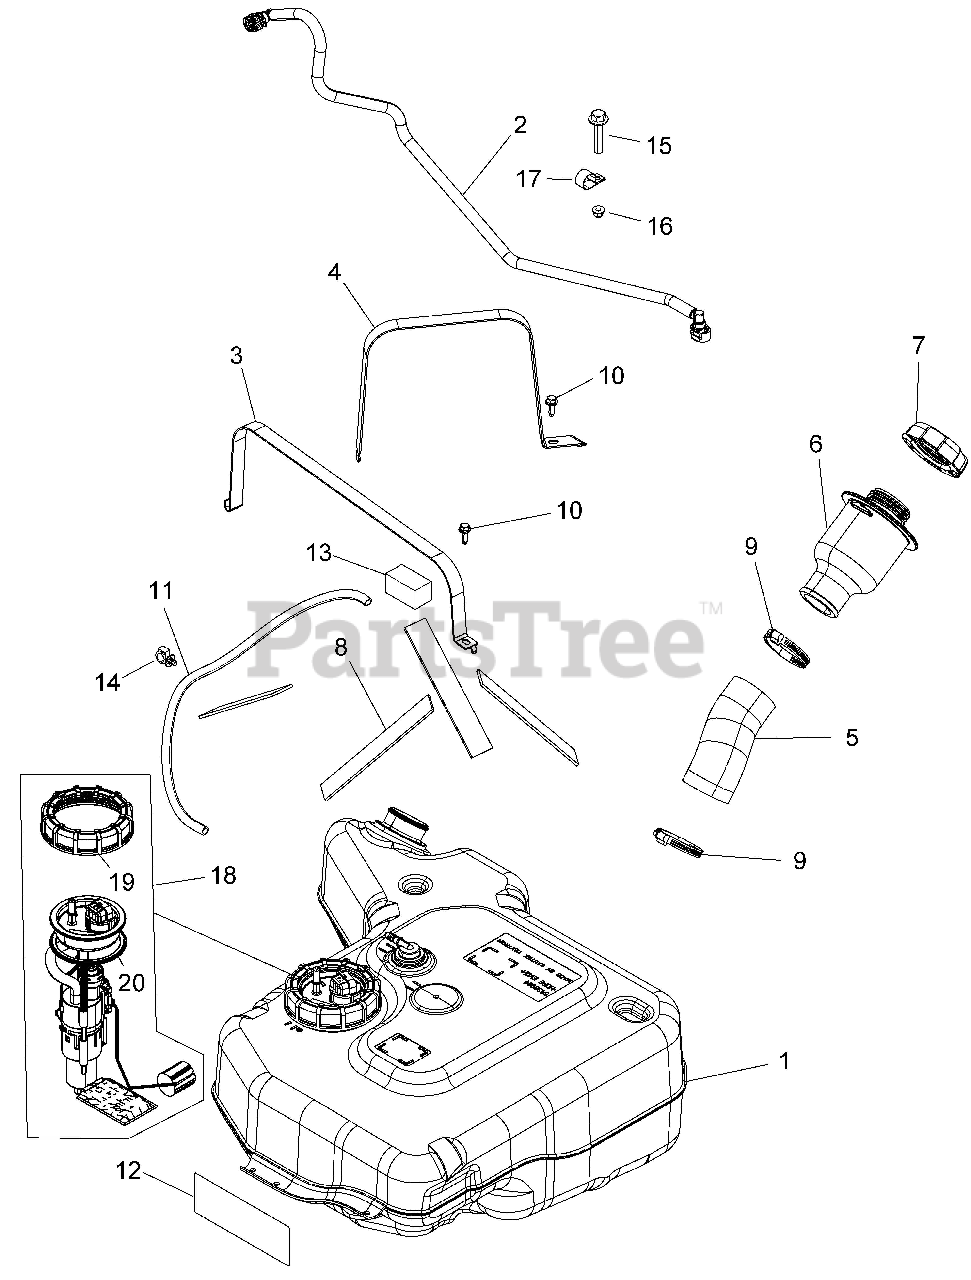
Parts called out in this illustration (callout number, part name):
1	ASM-FUEL TANK
2	ASM-FUEL LINE,RGR,570,FS
3	BRKT-TANK,STRAP,INSIDE,GALV
4	BRKT-TANK,STRAP,OUTSIDE,GALV
5	HOSE-FUEL FILL
6	ASM-FUEL INLET
7	CAP-GAS TANK
8	PAD, BATTERY
9	CLAMP,BAND,NARROW (10)
10	SCR-M6X1.0X20,HXHD,FLG,TDFM,BL
11	LINE-VENT,5/16 ID 50CM
12	FOIL-FENDER JOINT,RH
13	FILTER-VENT LINE
14	CLIP,ROUTING,.472 B.D.,HINGED
15	BOLT-M6X1.0X20,HXHD,FLG,BLK
16	NUT-M6X1.0,FLG-NYLOC-OLIVE D
17	CLIP,ROUTING,.472 B.D.,HINGED
18	KIT-FUEL PUMP REPLACEMENT,RNGR
19	NUT, JAM
